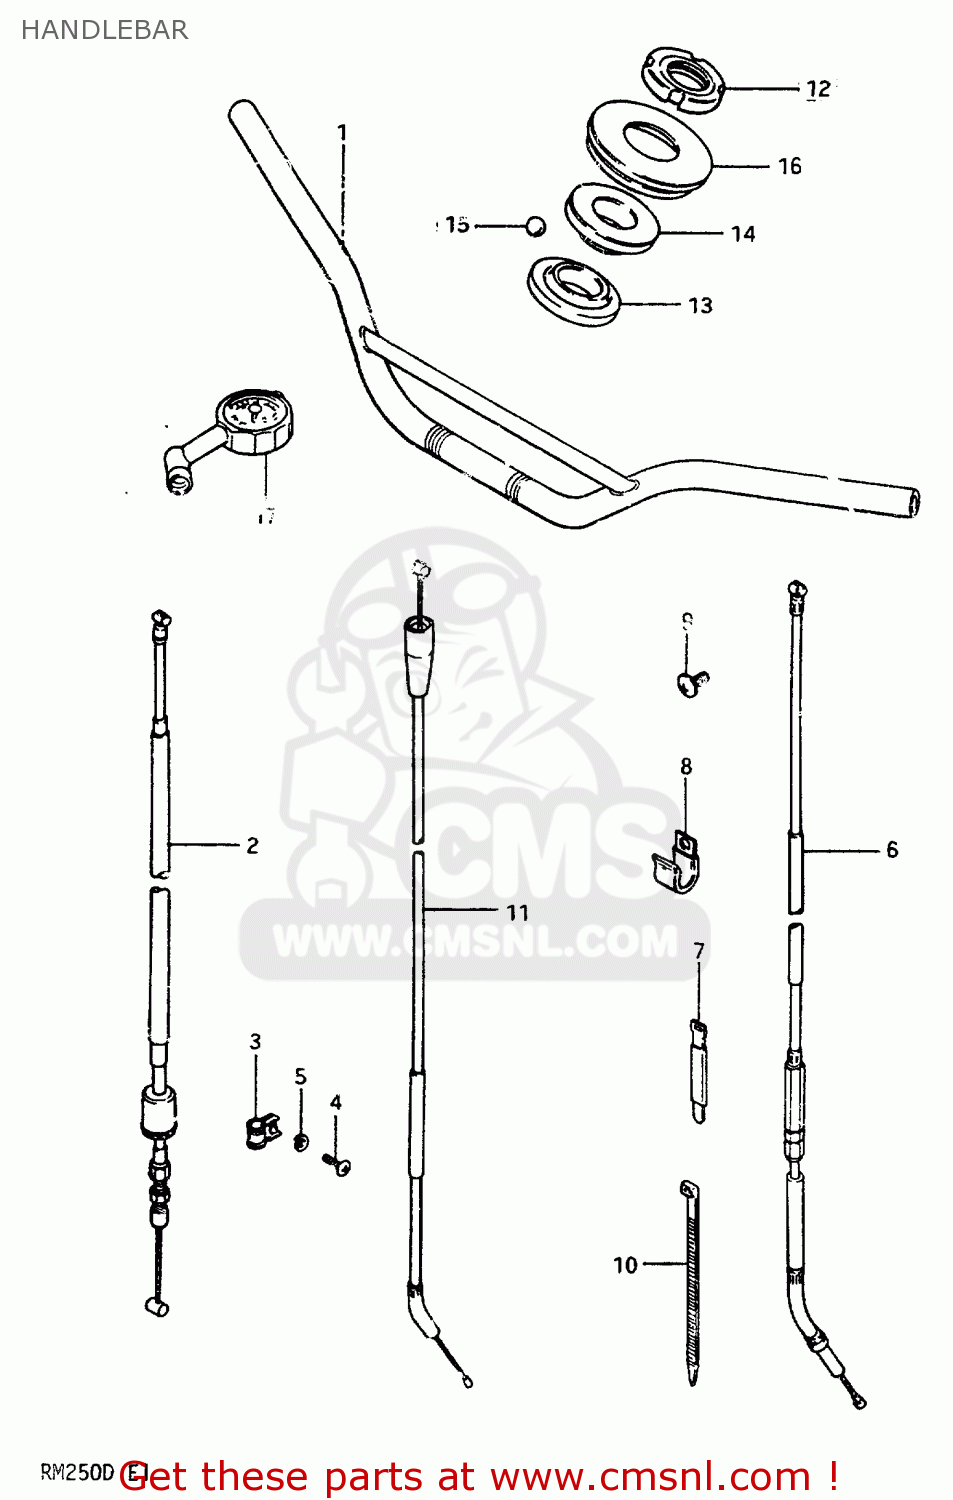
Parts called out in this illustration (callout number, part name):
1	HANDLEBAR
2	CABLE ASSY,FR BRAKE
3	GUIDE,CABLE
4	SCREW
5	WASHER,LOCK
6	CABLE ASSY,CLUTCH
7	CLAMP
8	CLAMP
9	SCREW
10	CLAMP
11	CABLE ASSY,THROTTLE
12	NUT,STEERING STEM
13	RACE,STEERING INNER (SUJ)
14	RACE,STEERING,OUTER,UPPER
15	BALL
16	SEAL,STEERING UPR DUST
17	GAUGE ASSY,AIR PRESSURE
